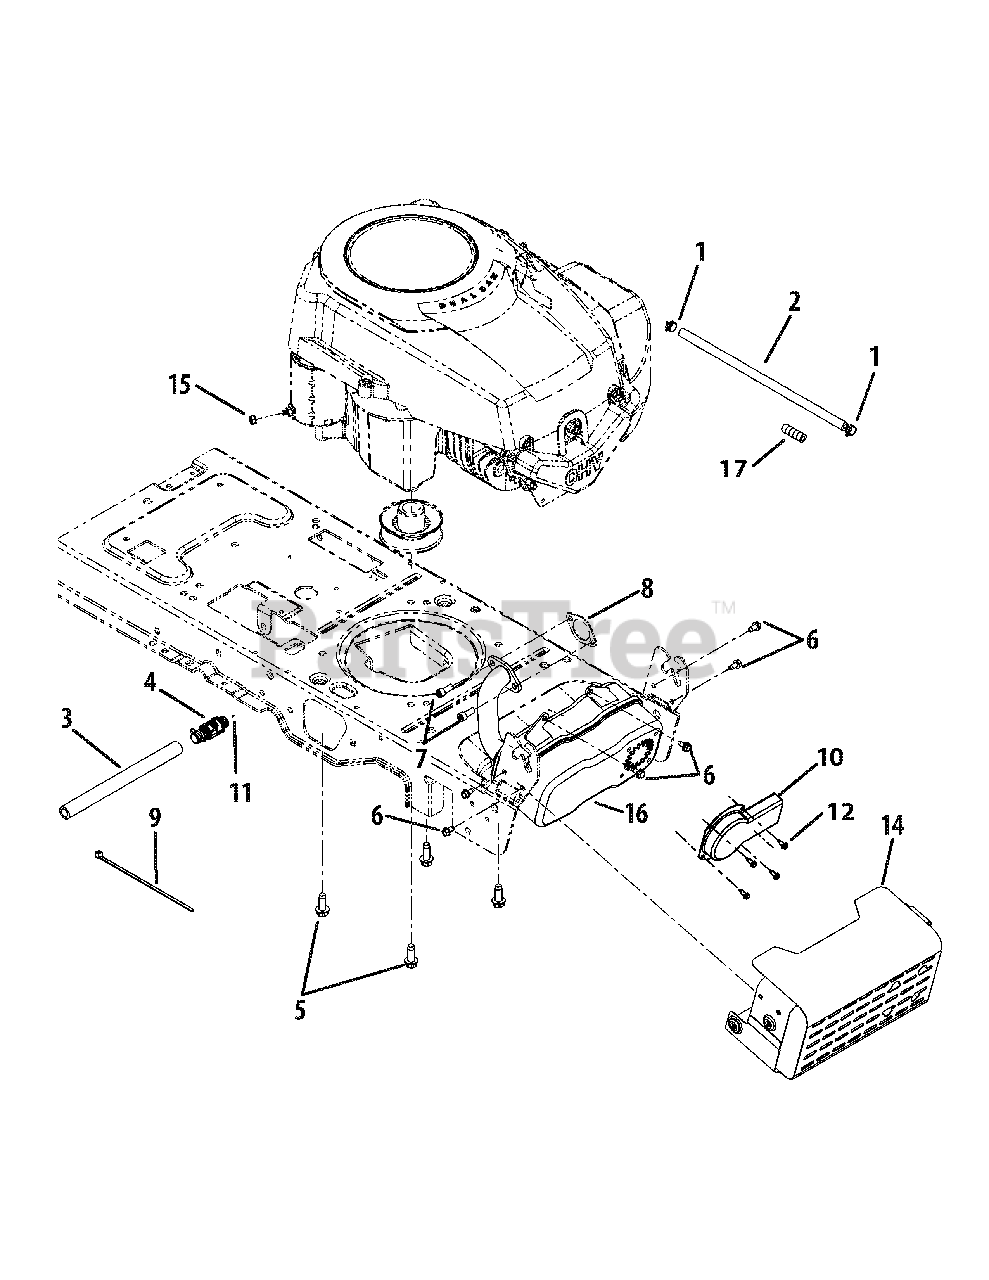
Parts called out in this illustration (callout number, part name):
2	Fuel Line 13" Lg.
3	Oil Drain Hose 9" Lg.
5	TT Screw 3/8-16 x 1.00
6	Hex Wash S-Tapp Scr 1/4-20 x .50
7	Scr. 5/16-18 x .75
10	Long Muffler Deflector
11	Pipe Sealant
12	Hex AB Scr #8-18 x .50
15	Hex Sems Nut 1/4-20
16	Muffler
17	Vent Hose (optional)
